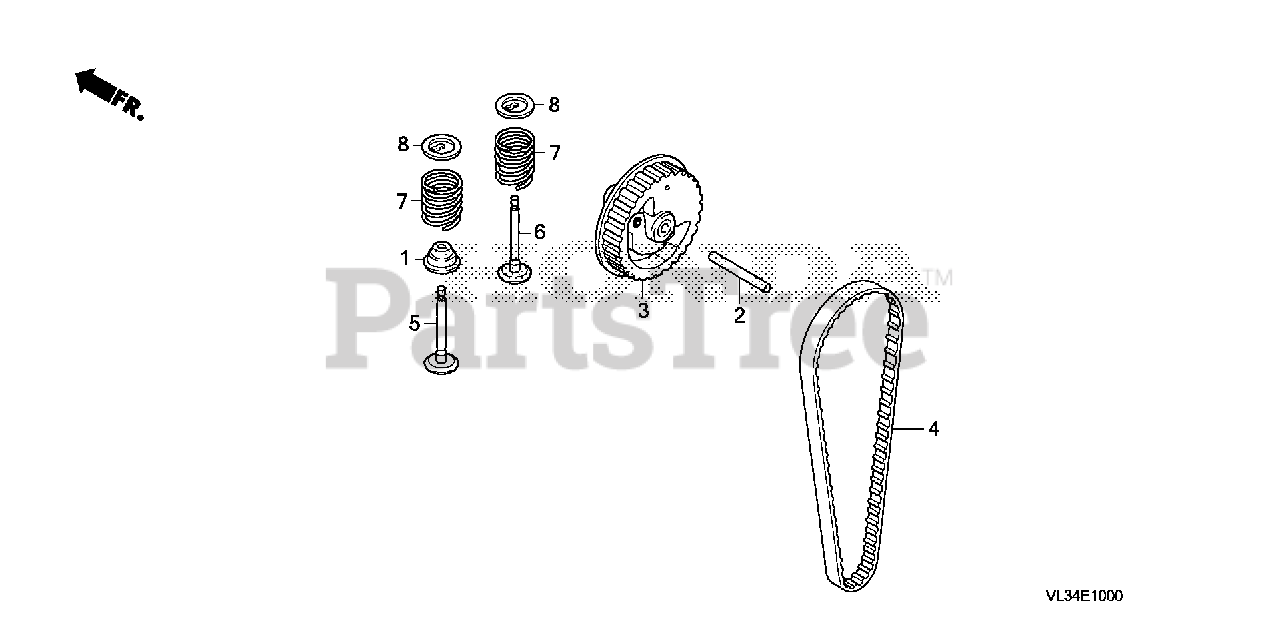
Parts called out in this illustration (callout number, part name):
1	SEAL, VALVE STEM
2	ROLLER (4X31.8)
3	PULLEY, CAMSHAFT
4	BELT, TIMING (76ZU5 G-310)
5	VALVE, IN. (FI)
6	VALVE, EX. (ZE)
6	VALVE, EX. (FE)
7	SPRING, VALVE
8	RETAINER, VALVE SPRING
